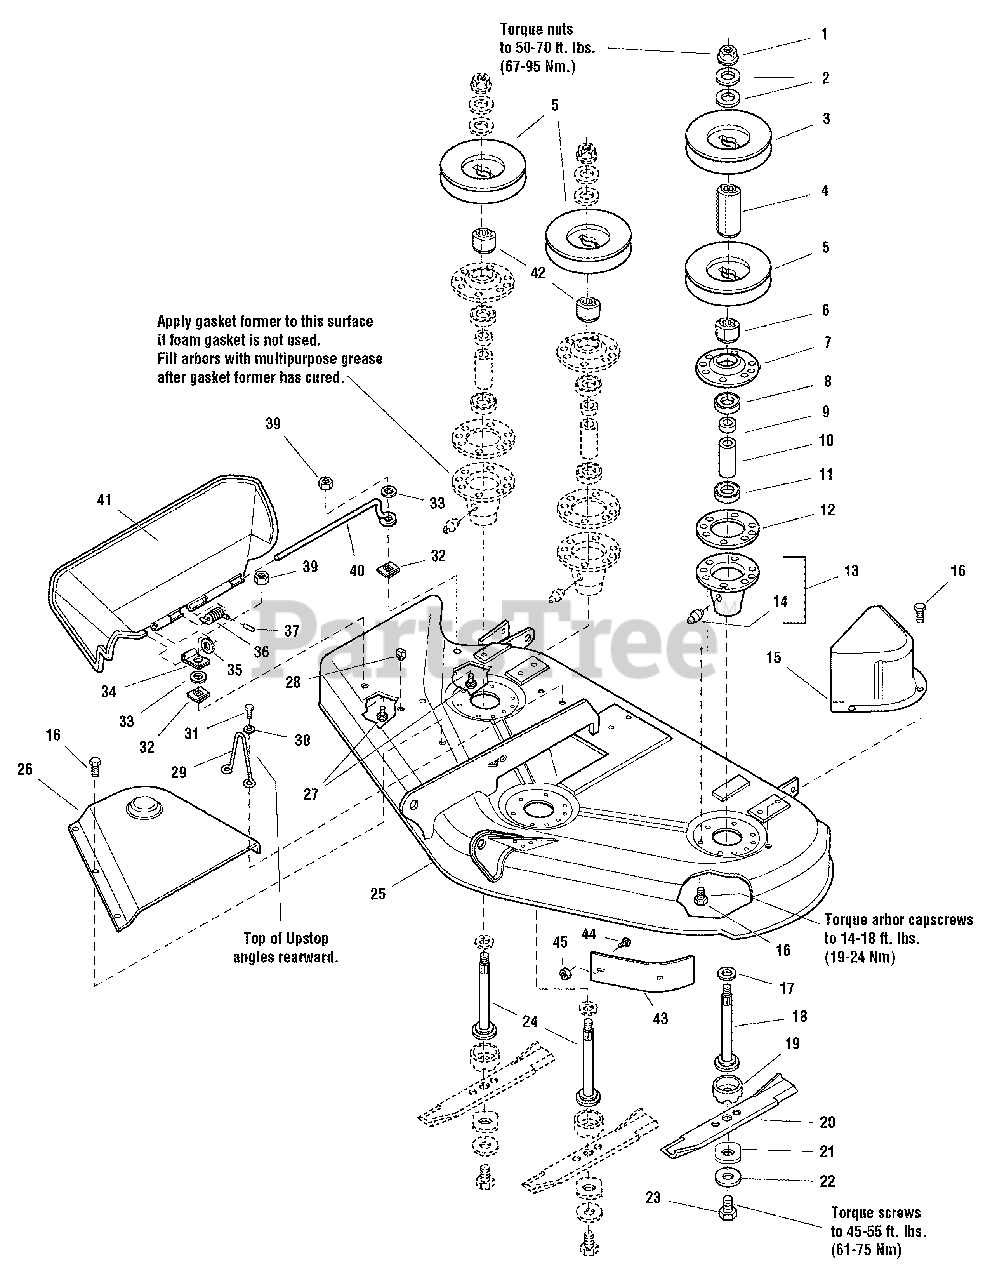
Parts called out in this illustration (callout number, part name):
1	NUT, Hex Flange, 9/16-18
2	WASHER, Bellevilled, 9/16
4	HUB, Double Pulley
6	HUB, Double Pulley
7	COVER, Arbor Housing
8	BEARING, Ball, 3/4 x 1-3/4 x 5/8
9	SPACER, 21/32 x 3/4 x 5/8
10	SPACER, 11/16 x 5/32 x 2-11/16
11	BEARING, Ball, 11/16 x 1-9/16 x 15/32
12	GASKET, Foam
13	HOUSING ASSEMBLY, Arbor Bottom, w/Lube Fitting
14	FITTING, Grease
15	COVER, Arbor
16	CAPSCREW, Hex Head Taptite, 5/16-18 x 3/4
17	WASHER, Bellevilled, 9/16, Black
18	SHAFT, Arbor (LH)
19	SHIELD, Grass, Lower
20	BLADE, Mower, 18-1/8
21	WASHER, Hex, 11/16 x 2
22	WASHER, Spring 15/32, Black
23	CAPSCREW, Hex Head, 7/16-14 x 1
24	SHAFT, Arbor (Center & RH)
25	MOWER HOUSING ASSEMBLY, 50" Mower (Orange)
25	MOWER HOUSING ASSEMBLY, 50" Mower (Red)
26	COVER, Arbor
27	CARRIAGE BOLT, 1/4-20 x 7/8
30	WASHER
31	CAPSCREW, Hex Washer Head Taptite, 5/16-18 x 3/4
32	NUT, Push
33	WASHER, 1/4, Black
35	WASHER, 5/16, Black
36	SPRING, Torsion
37	CAP, Spring End
39	NUT, Hex, 1/4-20 ESNA
40	ROD, Deflector, Front
41	DEFLECTOR, Plastic
42	HUB, Pulley, Center & RH
43	BAFFLE, Anti-Blowout
44	NUT, Hex, Whizlock, 5/16-18
45	CARRIAGE BOLT, 5/16-18 x 3/4
